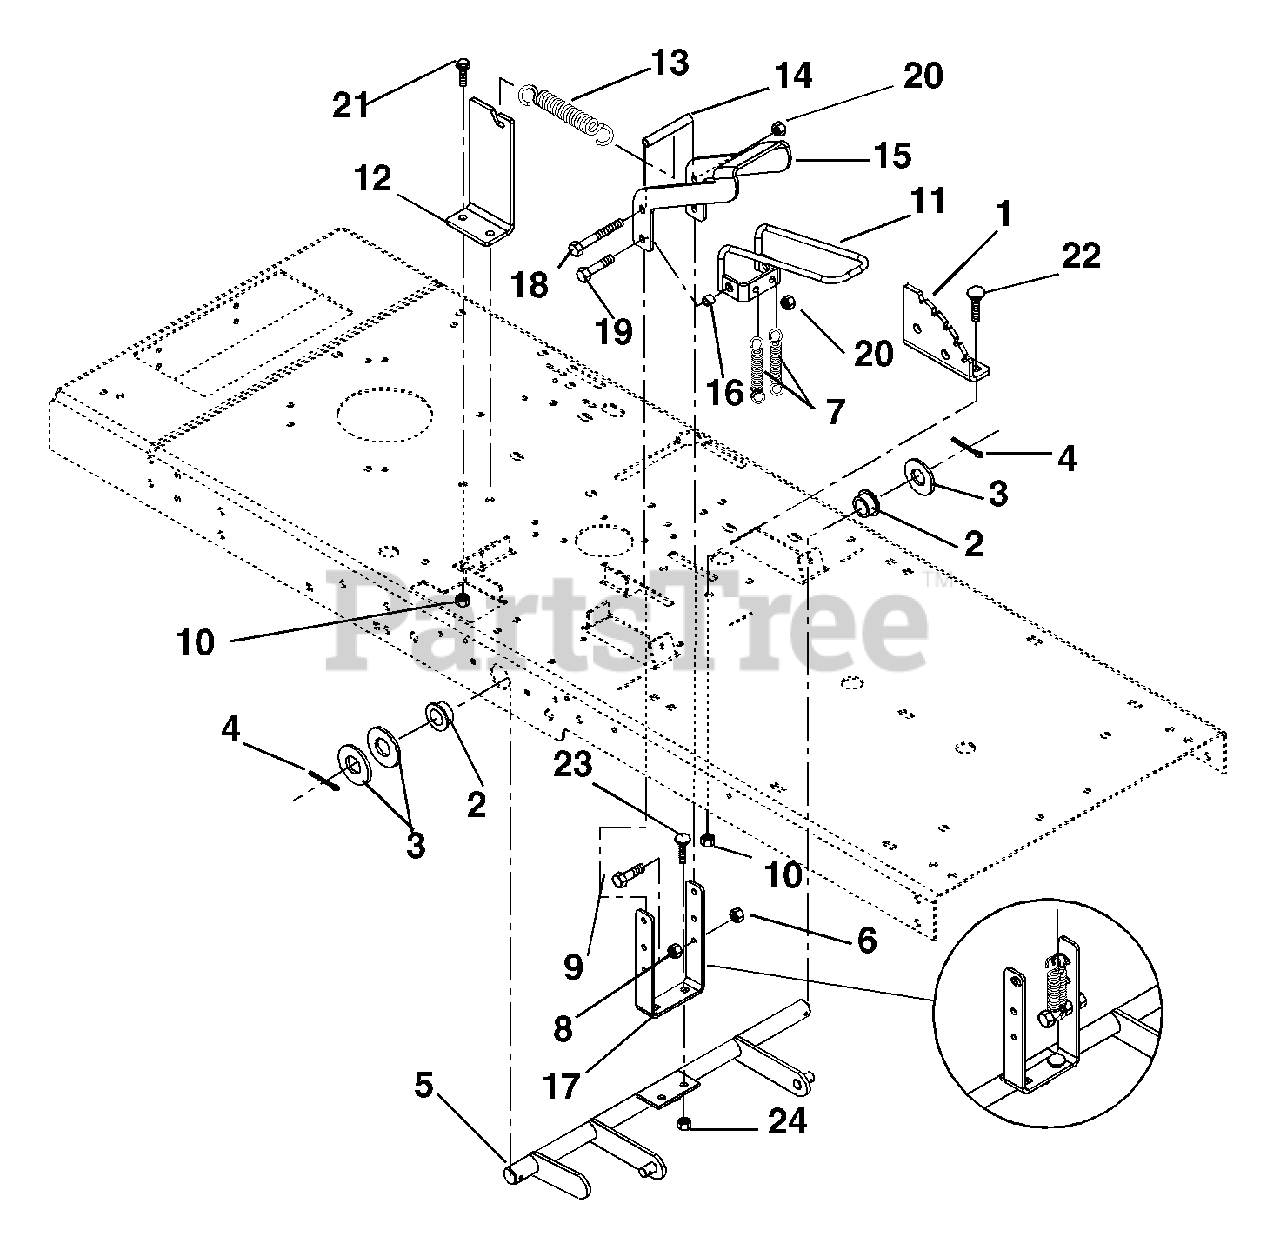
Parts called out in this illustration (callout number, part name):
1	Detent Plate
2	Bushing-Flange 1.020 x 1.385 x .75 x 1.75
3	Washer-Flat-Steel 1.062 x 2.000 x .134
4	Pin-Cotter .188 x 1.50
5	Lift Lever Weldment
6	Nut-Locking-Center .25-20
7	Spring-Tension .092 x .69 x 1.75
8	Nut-Hex .25-20
9	Bolt-Hex .25-20 x 2.00 Grade 5
10	Nut-Locking-Center .38-16
11	Weldment-Release
12	Bracket-LIft
13	Spring-Tension
14	Spacer .328 x .462 x 3.14
15	Handle-Deck Lift
16	Spacer .328 x .462 x .41
17	Bracket-Handle
18	Bolt-Hex .312-18 x 4.50 Grade 5
19	Bolt-Hex .312-18 x 1.25 Grade 5
20	Nut-Locking-Nylon .312-18
21	Bolt-Hex .38-16 x 1.00 Grade 5
22	Bolt-Round Head Square Neck .375-16 x .75 Grade 5
23	Bolt-Round Head Square Neck .375-16 x 1.00 Grade 5
24	Nut-Locking-Top Flange .38-16
